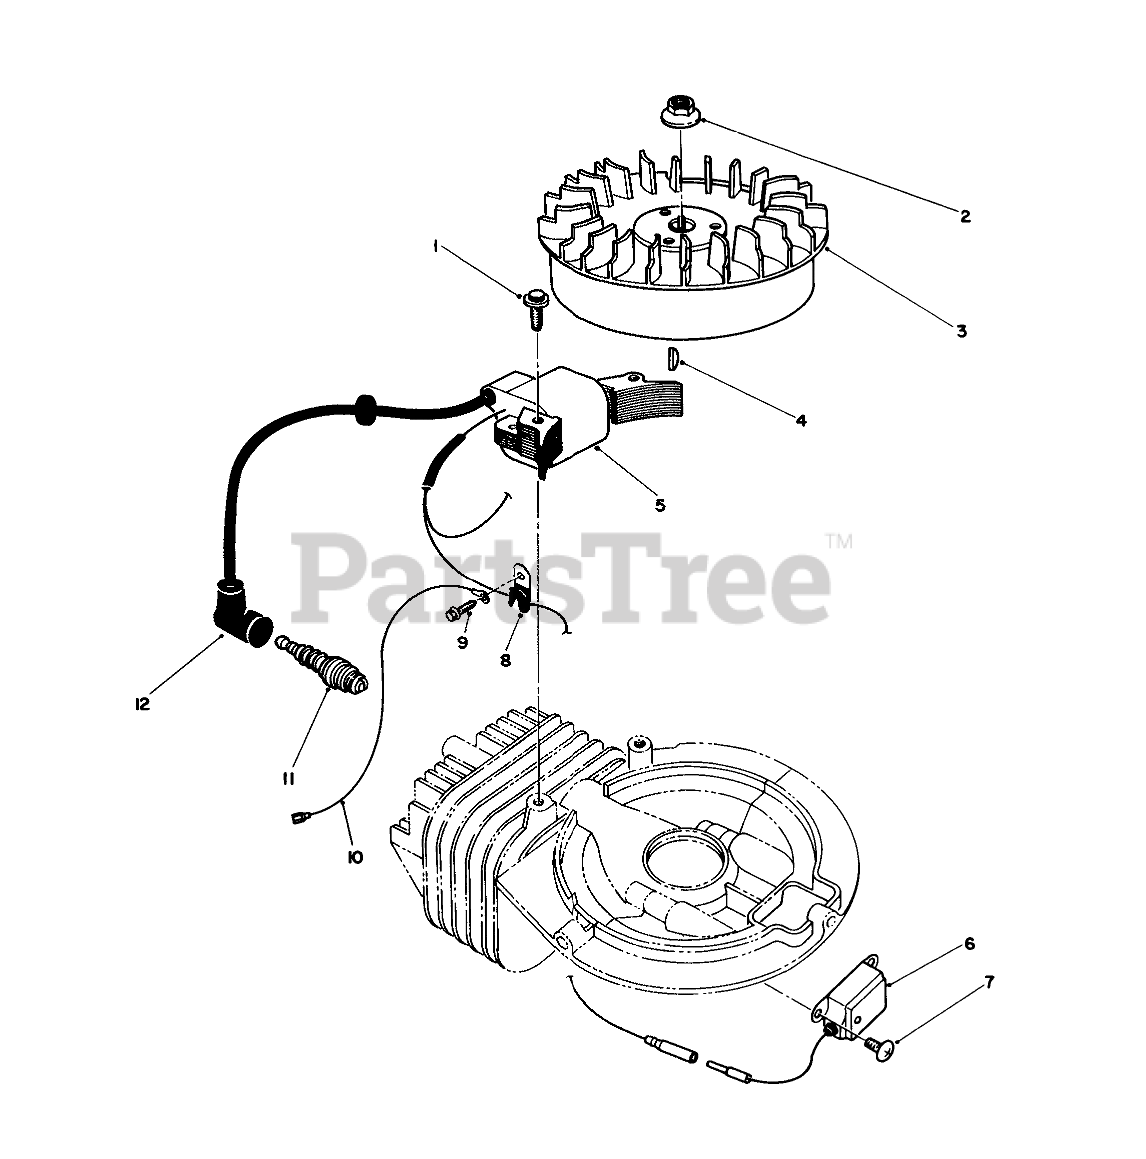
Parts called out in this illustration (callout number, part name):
1	Socket Hd. Capscrew
3	FLYWHEEL
5	MAGNETO COIL
6	MAGNETO MODULE
7	SCREW
8	CLAMP
11	Sparkplug
12	CAP-SPARKPLUG
